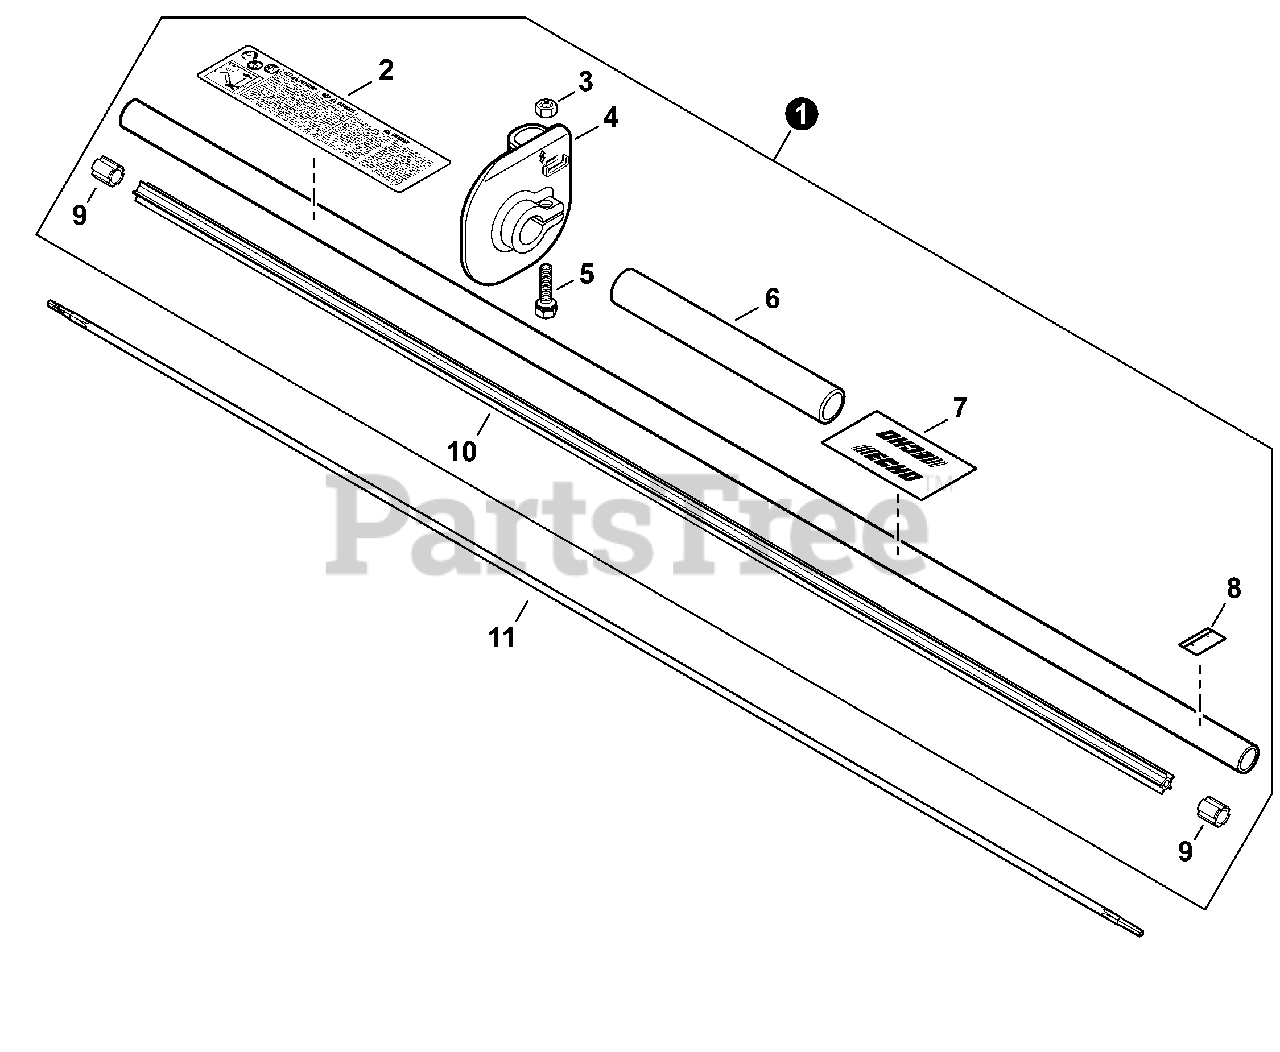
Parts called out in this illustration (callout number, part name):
1	MAIN PIPE ASSY
2	LABEL, CAUTION
3	NUT M5
4	GUARD, HAND
5	BOLT 5×20
6	GRIP, HANDLE
7	LABEL, HANDLE LOCATION
8	LABEL - ALIGNMENT
10	LINER, FLEXIBLE 21.6×1420
11	DRIVESHAFT - FLEXIBLE
